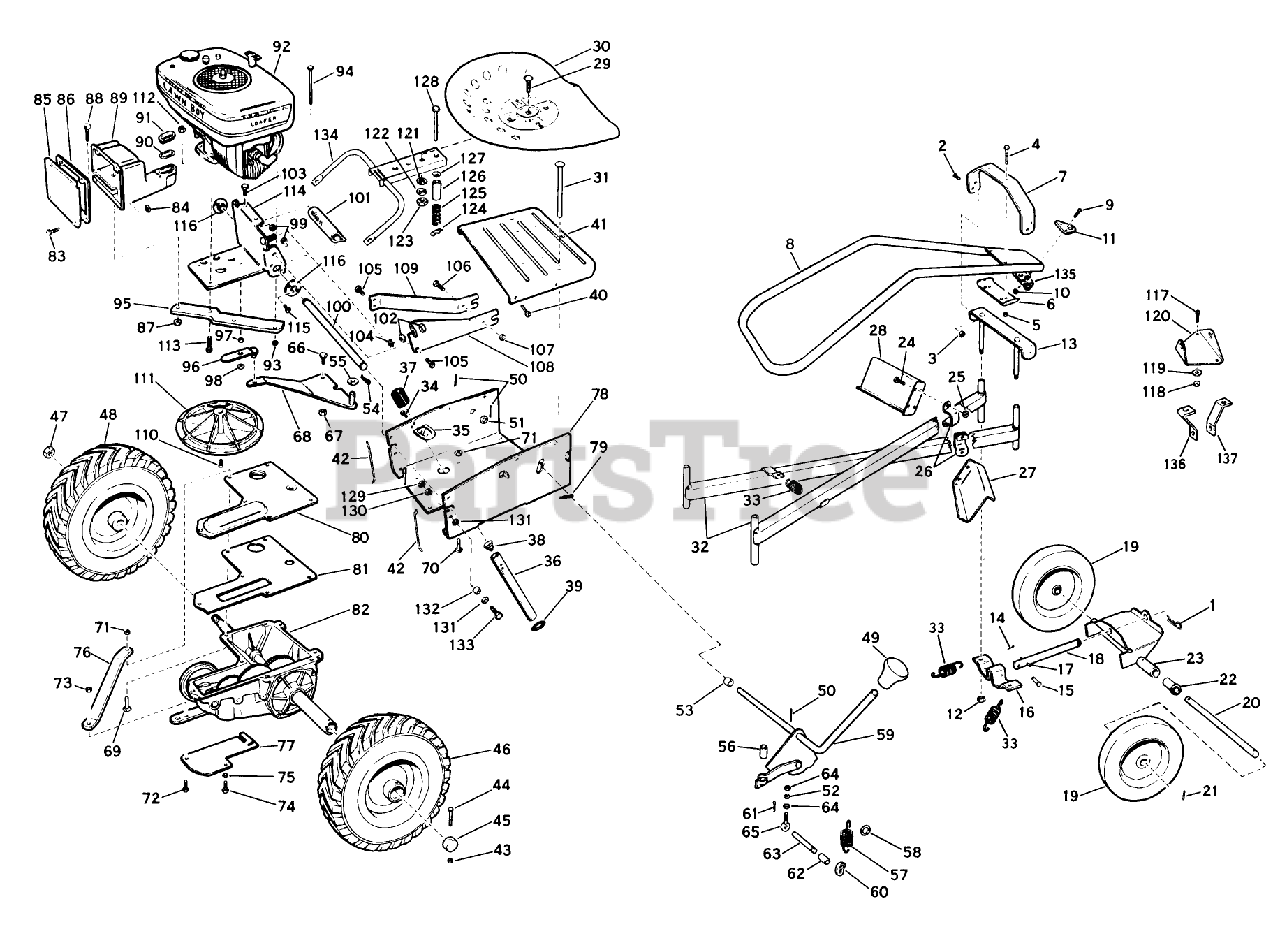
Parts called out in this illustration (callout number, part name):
2	Bolt-Handle
3	STOP NUT
10	STOP NUT
14	Cotter Pin
16	Pivot Bracket-Frame, Bottom
22	Bearing-Wheel, Nylon
29	Carriage Bolt-Seat to Cover
30	Seat Assembly
33	Spring-Clutch
39	Seal, Tube-Oil Filler
41	Cover-Shroud
44	Screw-Differential
52	WASHER, LOCK
53	Roller-Speed Control
57	Spring-Clutch
65	Bolt-Eye, Ramp Pin Adjustment
69	Screw-Shroud
74	Screw-Guard to Housing
78	Shroud-Frame
82	Transmission Assy.
87	Nut-Huglok
90	GASKET S
92	Engine-Model D-452
93	LOCKNUT E
100	Shaft-Engine Mounting Plate
104	WASHER, LOCK
107	STOP NUT
108	Arm-Clutch
116	Bearing-Engine Mounting
118	STOP NUT
125	Spring-Seat
126	Seat Snubber
128	Pin-Spring Guide
134	Seat Support Assembly
135	Bracket
136	Support
137	Bracket
